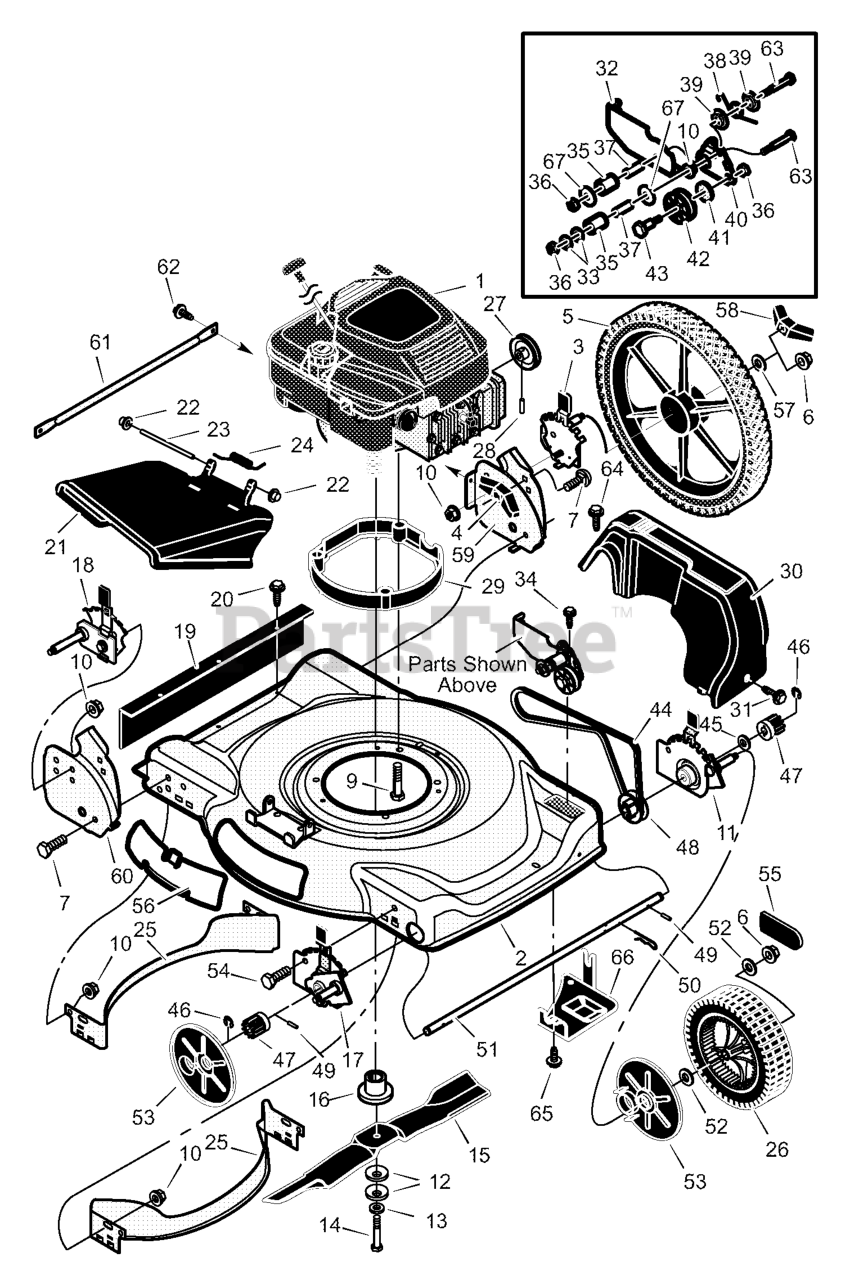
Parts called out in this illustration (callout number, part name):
1	Engine
2	Housing
3	Height Adjuster, Left Rear
5	Wheel and Tire, Rear
6	Locknut, Flange
7	Bolt, Carriage
9	Bolt, Engine
10	Nut
11	Height Adjuster, Left Front
12	Washer, Belleville
14	Bolt, Hex
15	Blade, Mulcher
16	Adapter, Blade
17	Height, Adjuster, Right Frt.
18	Height, Adjuster, Right Rr.
19	Guard, Rear
21	Deflector, Chute
22	Push-On Cap
23	Pin, Pivot
26	Wheel and Tire, Drive
28	Pin, Spring
29	Base, Engine
30	Cover, Belt (Black)
32	Bracket, Idler Support
33	Washer
35	Idler, Backside
36	Locknut
37	Bearing
40	Arm, Pivot
42	Pulley, Idler
43	Bolt, Shoulder
44	Belt, Briggs & Stratton
46	Ring, Retainer
47	Gear, Pinion
49	Pin, Drive
50	Pin, Hair
52	Washer
53	Cover, Dust
54	Bolt
55	Hub Cap
56	Plate, Mulch
58	Knob, Axle
59	Bracket, Left Handle
60	Bracket, Right Handle
66	Shield, Debris
